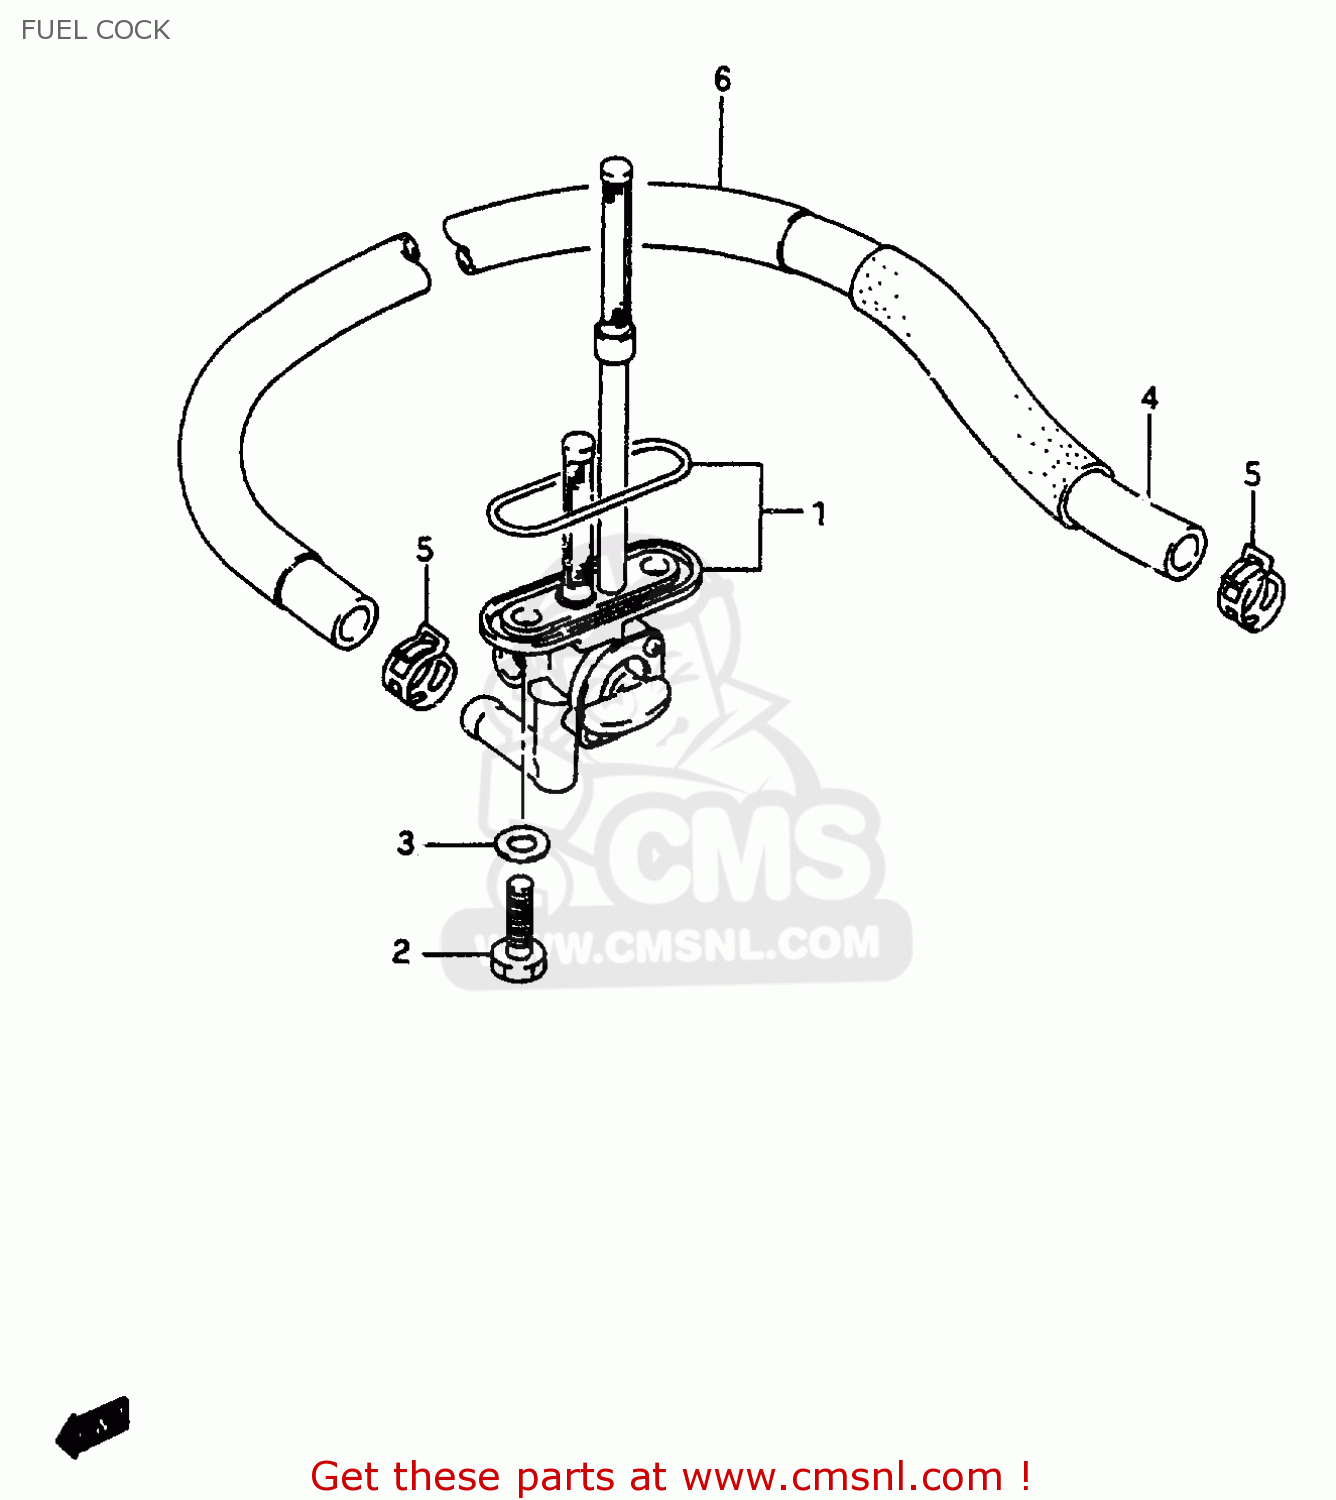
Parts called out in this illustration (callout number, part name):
1	COCK ASSY,FUEL
2	BOLT(6X20)
3	GASKET(6.4X11.5X0.8) (NAS)
4	HOSE,FUEL PUMP & COCK
5	CLIP
6	TUBE,FUEL HOSE
